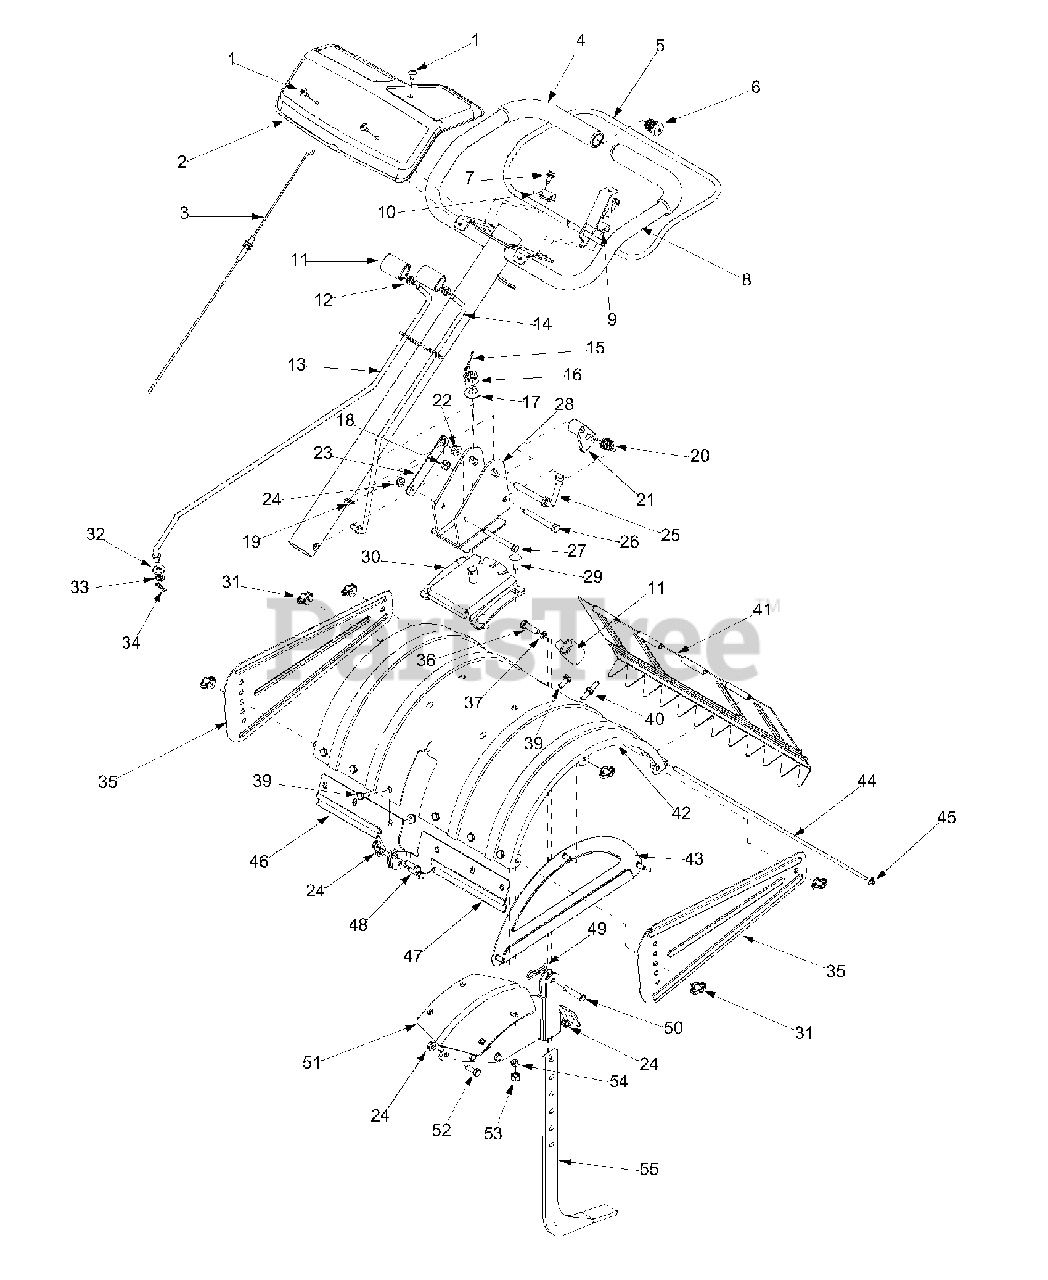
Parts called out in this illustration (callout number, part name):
1	Tap Screw 1/4-14 x .625
4	Foam Grip
6	End Plug
7	Hex Washer Screw 1/4-14 x .625
12	Jam Nut 3/8-16
13	Shift Control
14	Handle Adjustment Rod
15	Cotter Pin
16	Slotted Hex Nut 5/8
17	Bell Washer .64 ID x 1.25 OD
18	Hex Lock Nut 3/8-16
19	Cable Clip
20	Torsion Spring
21	Handle Swing Link
22	Flange Lock Nut 3/8-24
23	Retainer Bracket
24	Hex Flange Lock Nut 5/16-18
25	Adjustable Crank Handle
26	Hex Cap Screw 3/8-16 x 3.0
27	Hex Cap Screw 5/16-18 x 3.0
32	Rubber Washer .33 ID x .87 OD
33	Flat Washer .344 ID x .62 OD
34	Cotter Pin
36	Hex Cap Screw 3/8-16 x 1.25
37	Flat Washer .375 ID x .620 OD
39	Hex Cap Screw 5/16-18 x .75
40	Hex Screw 5/16-18 x .75
45	Cap Nut
48	Hex Cap Screw 5/16-18 x 1.0
49	Cotter Pin
50	Clevis Pin
53	Hex Nut 3/8-16
54	Lock Washer 3/8
